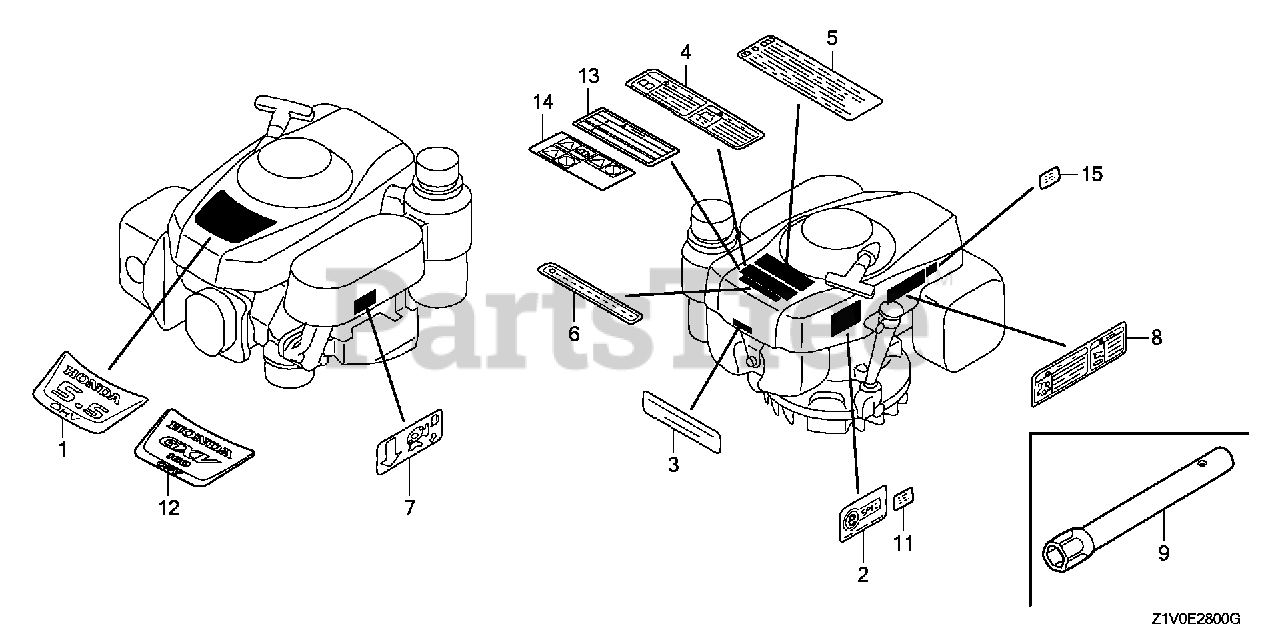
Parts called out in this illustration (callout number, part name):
1	MARK, EMBLEM (GXV160)
2	LABEL, E-SPEC (15.5X27.5)
3	MARK, MANUFACTURER
5	LABEL, CAUTION
7	MARK, FUEL PETCOCK CAUTION
9	WRENCH, BOX (P21)
